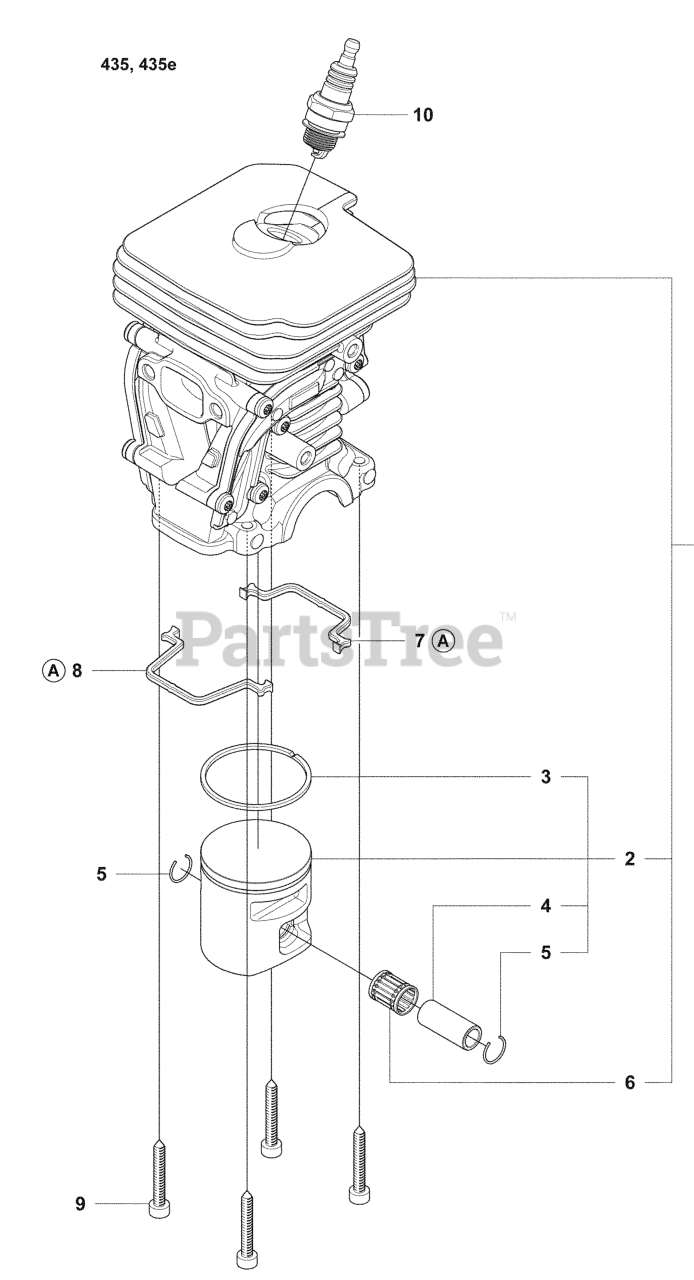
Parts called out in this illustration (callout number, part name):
1	ASSY, CYLINDER 435 & 435E
2	PISTON ASSY 435 435E
3	PISTON RING
4	PISTON PIN
5	CIRCLIP
6	SUPPORT BUSHING
7	GASKET
8	GASKET
9	SCREW MC6S 5X25
10	SPARK PLUG M14X1.25 NGK BPMR7A
